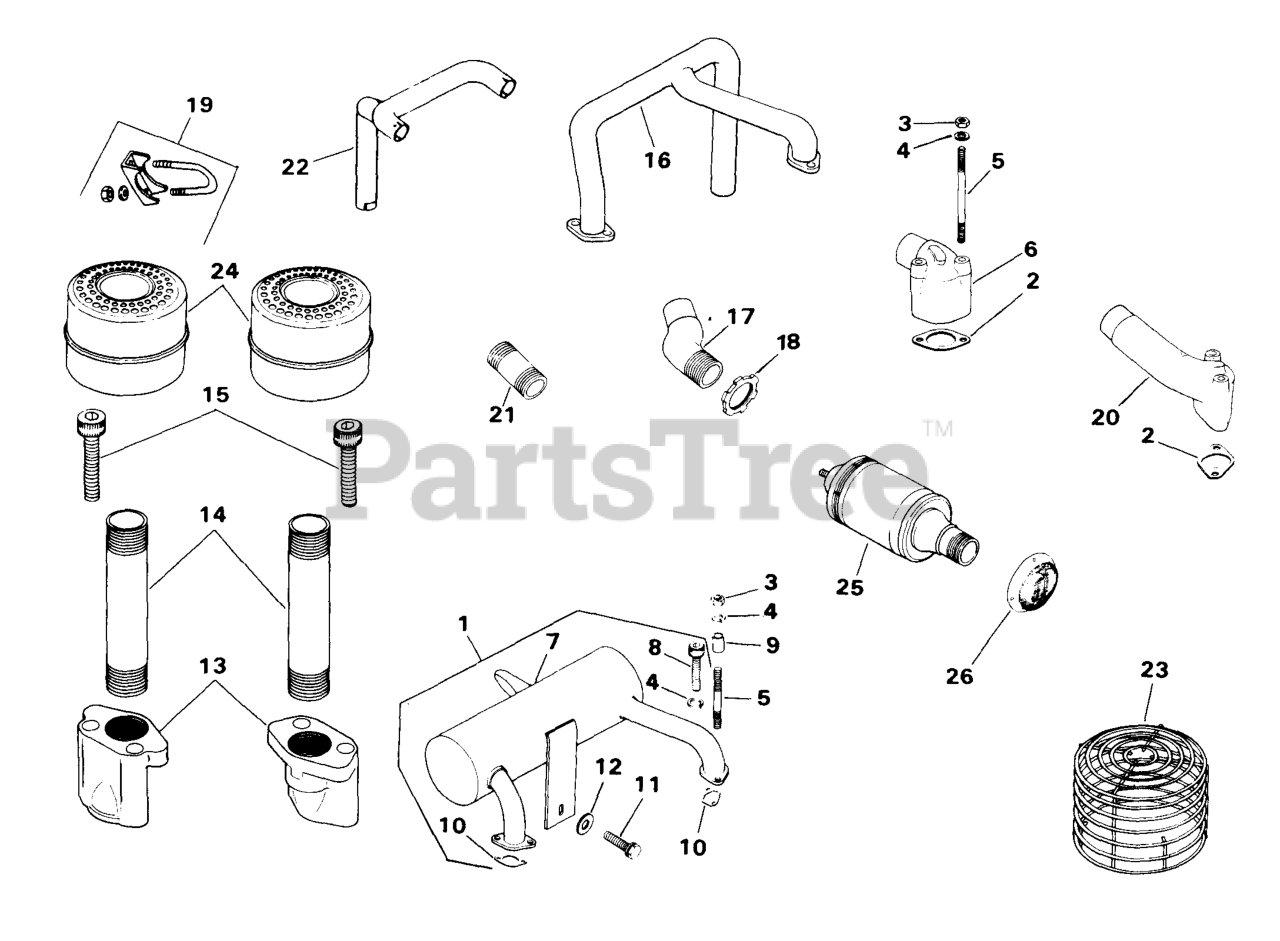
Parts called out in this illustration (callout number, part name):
4	WASHER, SPRING LOCK 5/16"
7	MUFFLER - DISCONTINUED
8	SCREW, HEX SOCKET HEAD CAP USE 25 086 87-S
11	SCREW, SEMS 1/4-20X5/8" USE 25 086 539-S
